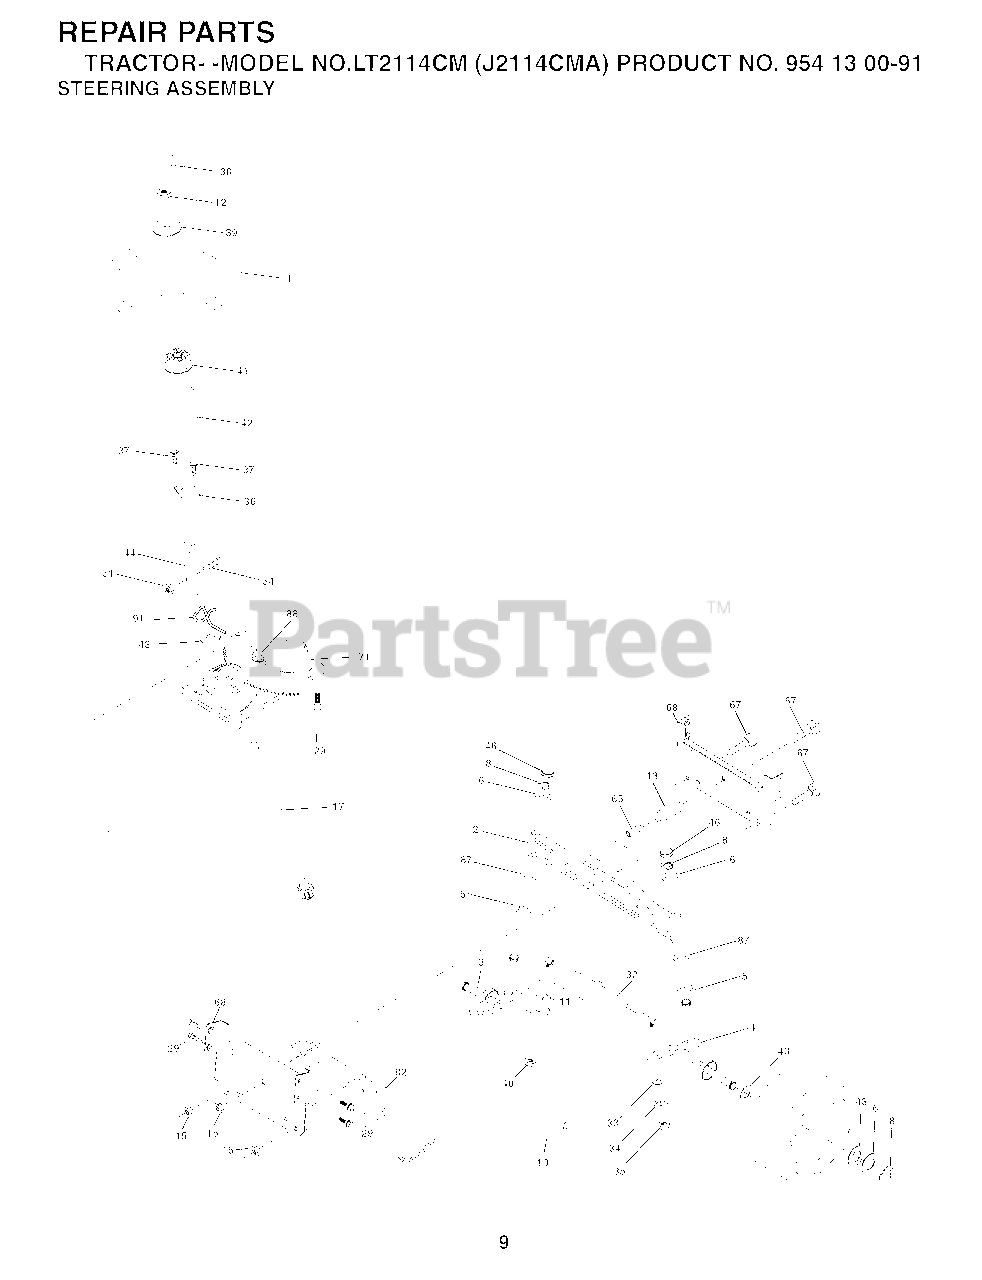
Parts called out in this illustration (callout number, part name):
2	AXLE ASM
3	SPINDLE.ASM.LH.15"TIRES
4	SPINDLE.ASM.RH.15"TIRES
8	RING CLIP
10	DRAGLINK.15".TIRES.2001
11	WASHER, LOCK 3/8
12	NUT.HEX.1/2-20
13	TUBE, PIVOT AXLE
15	NUT
17	SHAFT ASM, STEERING
29	SCREW 3/8-16X3/4
32	ROD.ASM.TIE.BALL.JOINT.NOVAN
33	WASHER M
34	LOCKWASHER
35	NUT, CROWNLOCK
36	BUSHING, STEERING
40	GRIPCO NUT
41	STEERING WHEEL ADAPTOR
42	BOOT.STEERING.SHAFT.BLACK
44	EXT, STEERING SHAFT
46	CAP.SPINDLE
51	CROWN LOCKNUT
65	SPACER BRACE AXLE
67	BOLT
68	BRACE.AXLE.15"TIRES
71	STEERING ASM
82	BRACKET
87	WASHER, FLAT .781 X 1 1/2"
88	BOLT, SHOULDER 7/16-20
91	CLIP.STEERING
